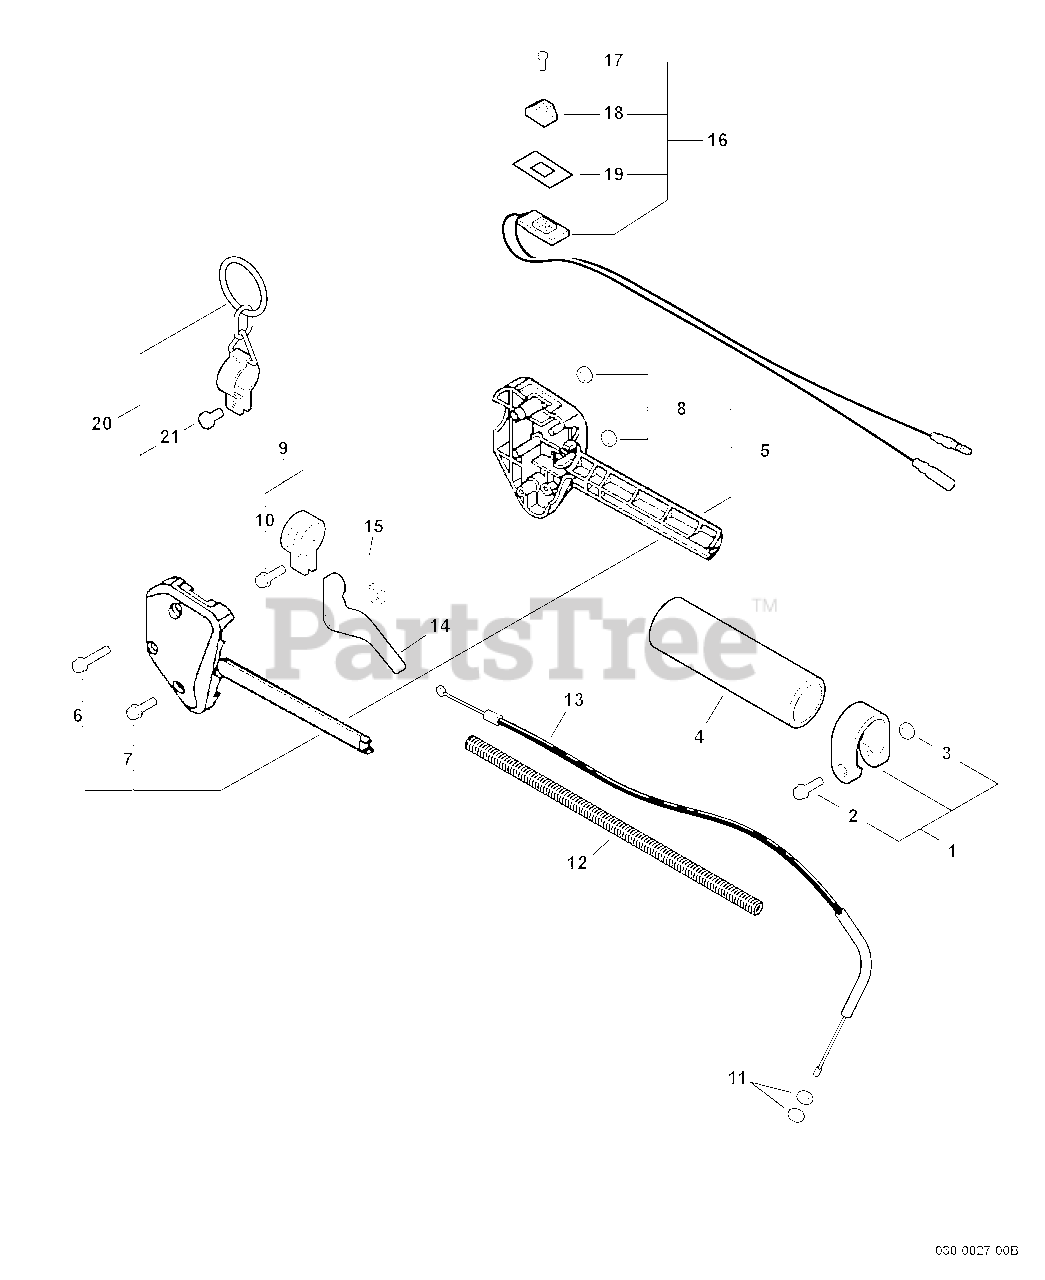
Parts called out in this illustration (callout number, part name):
1	CLAMP KIT
2	SCREW - 5X28
4	GRIP, HANDLE
5	CONTROL HANDLE KIT
6	SCREW - 5X35
7	SCREW - 5X25
9	CLAMP KIT
10	SCREW - 5X14
12	TUBE, PROTECTIVE - CORRUGATED
13	CABLE, THROTTLE
14	TRIGGER, THROTTLE
15	SPRING, TRIGGER
16	IGNITION SWITCH ASSY
17	SCREW - 3X10
18	KNOB, SWITCH - ORANGE
19	COVER, SWITCH - STOP
20	HANGER KIT
21	BOLT - 5X12
